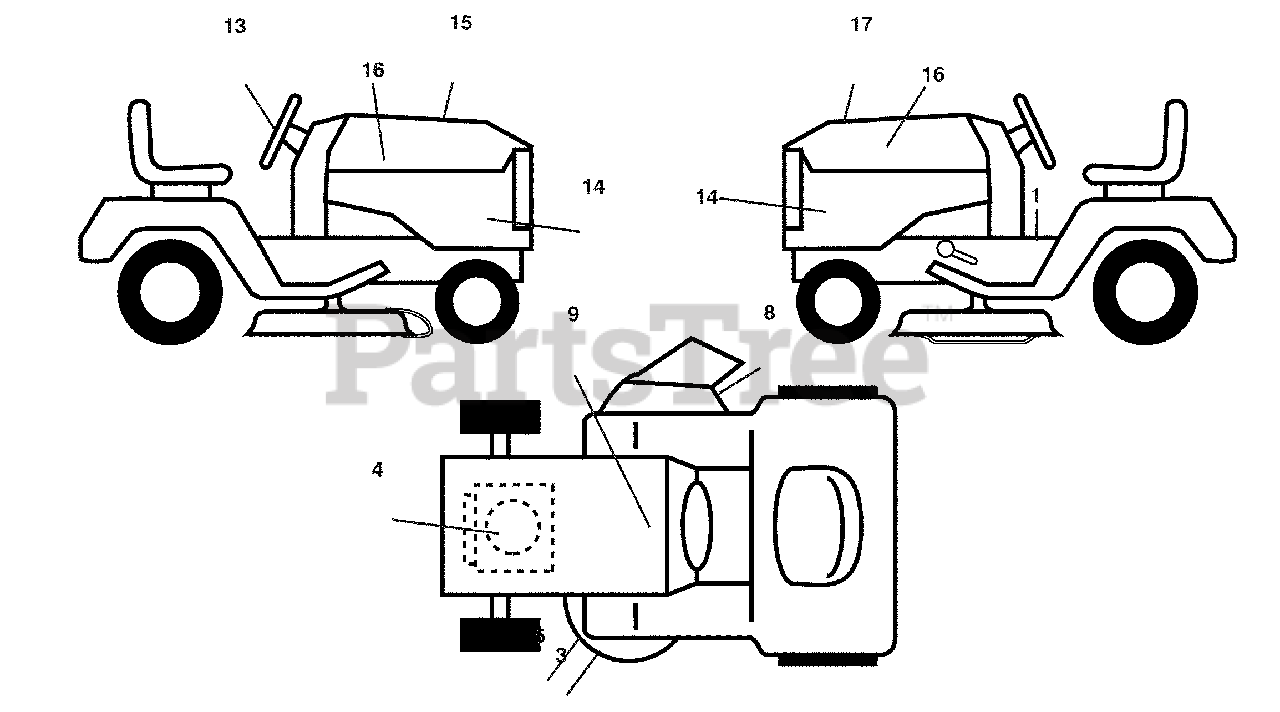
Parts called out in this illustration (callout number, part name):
1	Decal, Warning
3	Decal, Warning
4	Decal, Engine HP
5	Decal, Mower Caution
8	Decal, Mower Sch.
9	Decal, Battery Dnge/Poi
13	Decal, Steering Whl
14	Decal, Panel Side
15	Decal, Cust. Resp.
16	Decal, Hood Logo
17	Decal, Replacement
